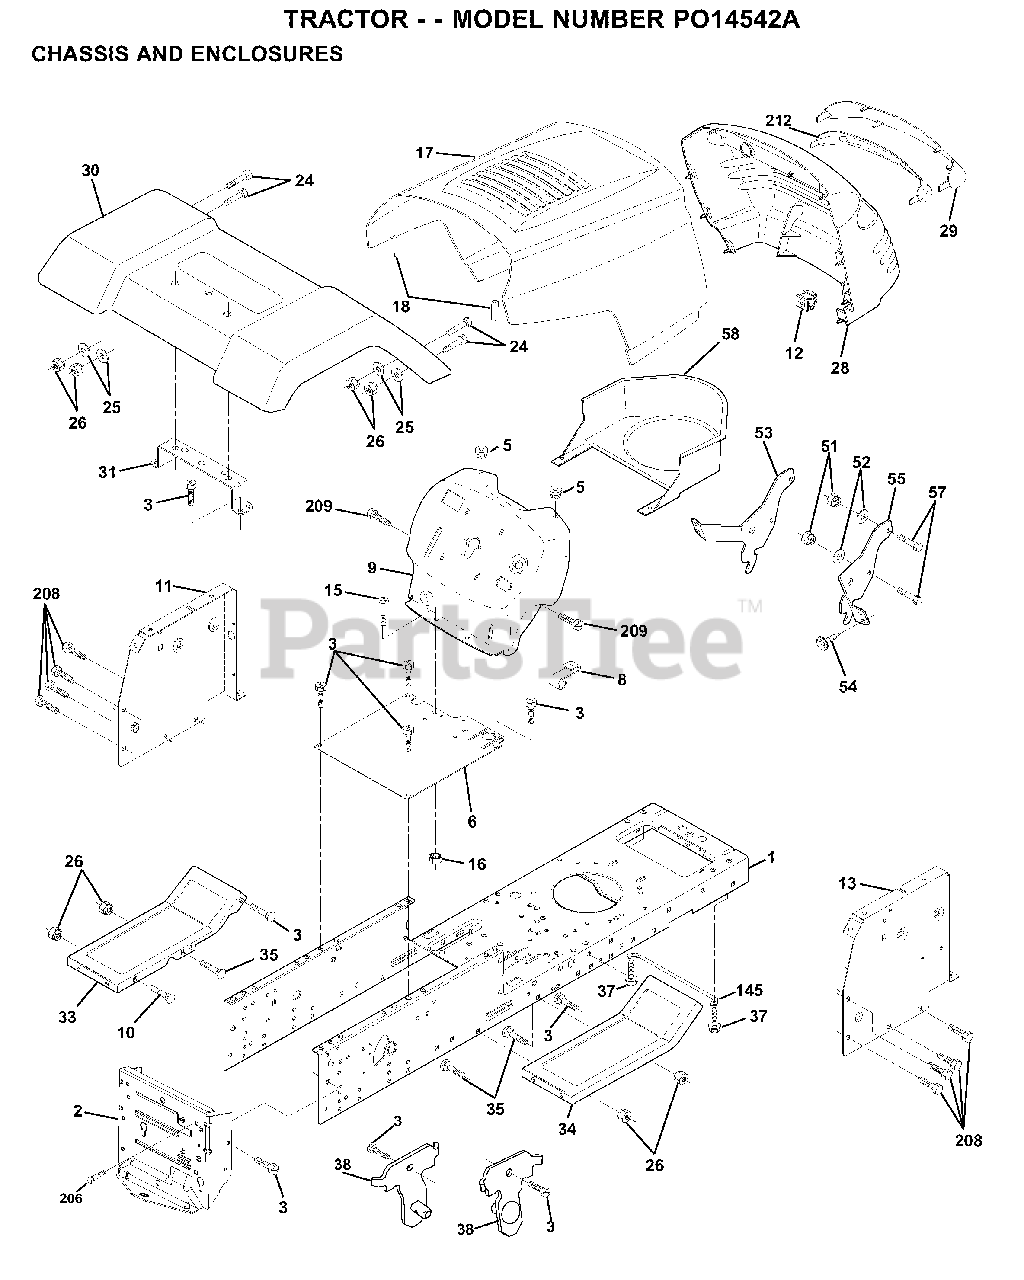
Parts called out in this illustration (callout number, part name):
2	Drawbar
3	Screw 3/8-16 x 3/4
5	Bumper Hood/Dash
6	Saddle Slkscr Flat Lt 5 Sp
8	Clip Retainer Slide-On
9	Dash
10	Bolt Rd Hd Sqnk. 3/8-16 Unc x 1
11	Panel Asm. Dash Lh
12	Clip Tinnerman Grile P/L
15	Screw Mach Trhd 5/16-18 Unc x 3/4
16	Nut Keps 5/16-18 Unc
17	Hood
18	Bumper Hood
24	Bolt Fin Hex 3/8-16 Unc x 1 Gr. 5
25	Washer 13/32 x 13/16 x 12 Ga.
26	Nut Lock Hex w/Insert 3/8-16 UNC
28	Grill Private Lable Blk
29	Lens Grille Private label
30	Fender Asm
31	Bracket Fender
33	Footrest
34	Footrest
35	Bolt Rd Hd Sht. Sqnk. 3/8-16 x 3/4
37	Screw Thdrol 5/16-18 x 1/2 Tyt
38	Bracket Asm. Pivot Mower Rear
51	Nut Lock Hex W/Ins. 1/4-20
52	Washer 9/32 x 7/8 x 16 Ga.
53	Bracket Grille LH
54	Screw Hex Wshd 8-18 x 7/8
55	Bracket, Grille RH
57	Bolt Fin Hex 1/4-20 x .75
58	Air Duct Private Label
145	Rod Pivot Chassis/Hood
206	Bolt shoulder 5/16-18
208	Screw Thdrol 3/8-16 x 1/2
209	Screw Hex Wsh Thdrol 3/8-16
212	Insert Lens Reflector
